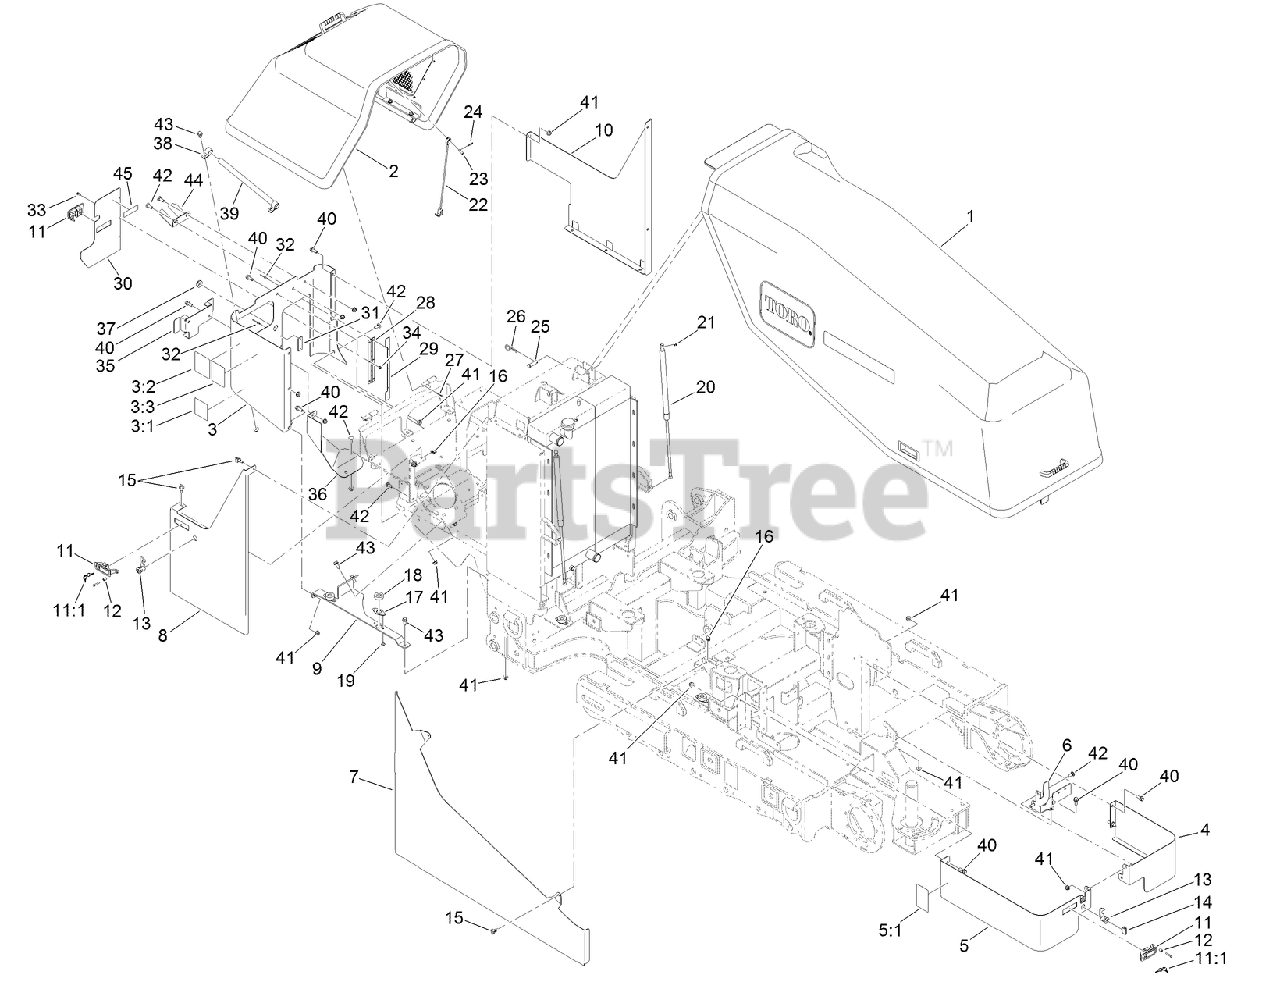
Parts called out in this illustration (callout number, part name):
2	REAR HOOD ASM
3	REAR PANEL ASM
3:1	DECAL-WARNING
3:2	DECAL-DANGER, NO RIDERS, REAR
3:3	DECAL-DANGER, BACK UP
4	PANEL-FRONT, LEFT
5	RIGHT FRONT PANEL ASM
5:1	DECAL-WARNING, THROWN OBJECTS
6	BRACKET-VALVE AND HOOD
7	PANEL-SERVICE, FRONT
8	PANEL-SERVICE, REAR
9	BRACKET-MOUNT, SERVICE PANEL
10	PANEL-LEFT SIDE, REAR
11	LATCH-TRIGGER, RAISED (W/LOCK)
11:1	KEY-REPLACEMENT
12	SPACER
13	LATCH
14	KEY-LATCH, HOOD
15	KNOB-STAR, THREE
16	NUT-SPEED
17	PLATE-GROMMET
18	GROMMET
19	RIVET-POP
20	SPRING-GAS, NON LOCKING
21	CLIP-LOCKING, GAS SPRING
22	CABLE-HOOD
23	PIN-CLEVIS
25	PIN-CLEVIS
26	PIN-HAIR
27	PIN-COTTER
29	PLATE-FILL, HINGE
30	DOOR-REAR
31	PLATE-FILL, LATCH
33	SCREW-HWH
34	NUT-HF
35	BRACKET-REEL, CABLE
36	PANEL-CABLE
37	GROMMET
38	CLAMP-R
39	TUBE-STAKE
40	SCREW-HHF
41	NUT-HF, NI
42	SCREW-CARR
43	SCREW-HHF
44	BRACKET-CRADLE, PENDANT
45	DECAL-ARRESTER, SPARK
